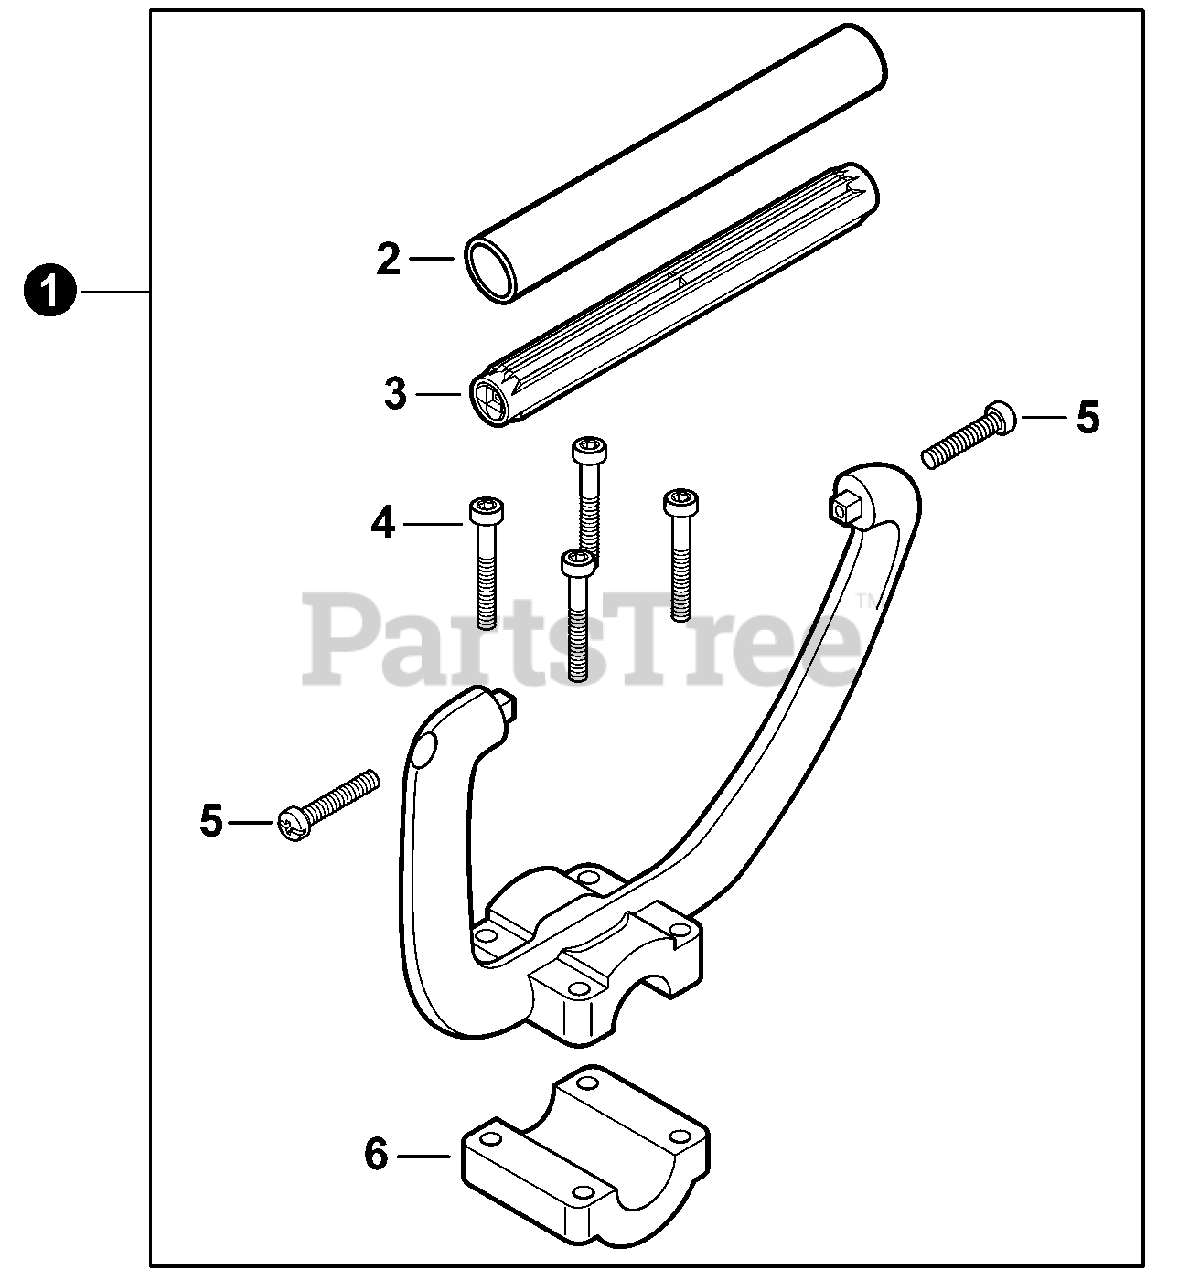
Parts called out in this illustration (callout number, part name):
1	HANDLE ASSY - SUPPORT
2	GRIP, HANDLE
4	BOLT 5×35
5	SCREW 5×30
6	BRACKET, HANDLE
